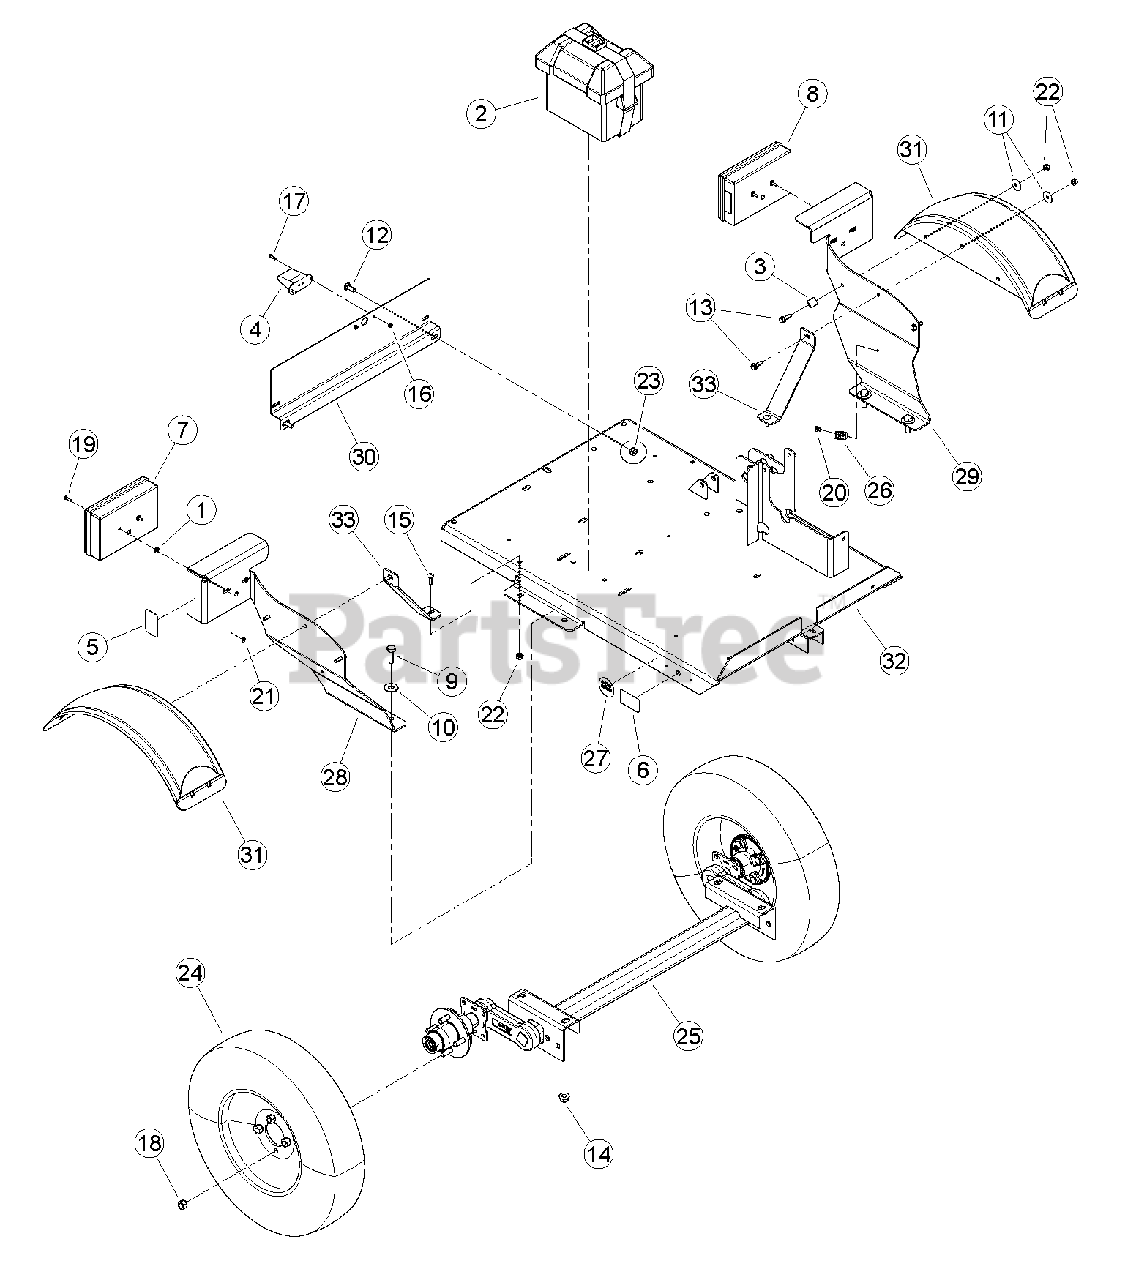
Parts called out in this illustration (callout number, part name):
1	GROMMET, 1/4 X 5/8 RUBBER
2	BOX, SMALL BATTERY
3	CLAMP, 9/16 COATED
4	LIGHT, LICENSE PLATE
5	REFLECTOR, WIDE ANGLE RED
6	REFLECTOR, WIDE ANGLE AMBER
7	LIGHT, TAIL RH
8	LIGHT, TAIL LH
9	BOLT, 1/2-13 X 1-1/2 HEX HD GR5
10	WASHER, 1/2 FLAT
11	WASHER, 5/16" FENDER ZP
12	BOLT, 3/8-16 X 1 GR5 CRG
13	BOLT, 5/16 X 1 FLANGE NC
14	NUT, 1/2-13 NYLOCK FLANGE
15	BOLT, 5/16-18 X 1 GR5 CRG
16	NUT, 10/24 NYLOCK TYPE NM ZP
17	SCREW, MCH #10-24 X 3/4"PAN HD PH ZP
18	NUT, 1/2-20 WHEEL
19	BOLT, 10-24 X 3/4" HHCS GR8 PLAIN
20	RIVET, AL BLIND 1/4 X 3/4 DOME HEAD
21	NUT, #10-24 K-LOCK ZP
22	NUT, 5/16-18 NYLOCK FLANGE
23	NUT, 3/8-16 NYLOCK FLANGE
24	ASSEMBLY, 5.30-12 TIRE + SPOKE RIM
25	AXLE, 1000 LB TORSION
26	CLAMP, CABLE MOUNT
27	DECAL, NATM COMPLIANCE
28	BRACKET, RH FENDER "CE"
29	BRACKET, LH FENDER "CE"
30	PLATE, MOUNTING
31	FENDER, BLACK PLASTIC DRILLED
32	WELDMENT, CHIPPER TRAILER
33	BRACKET, FENDER
